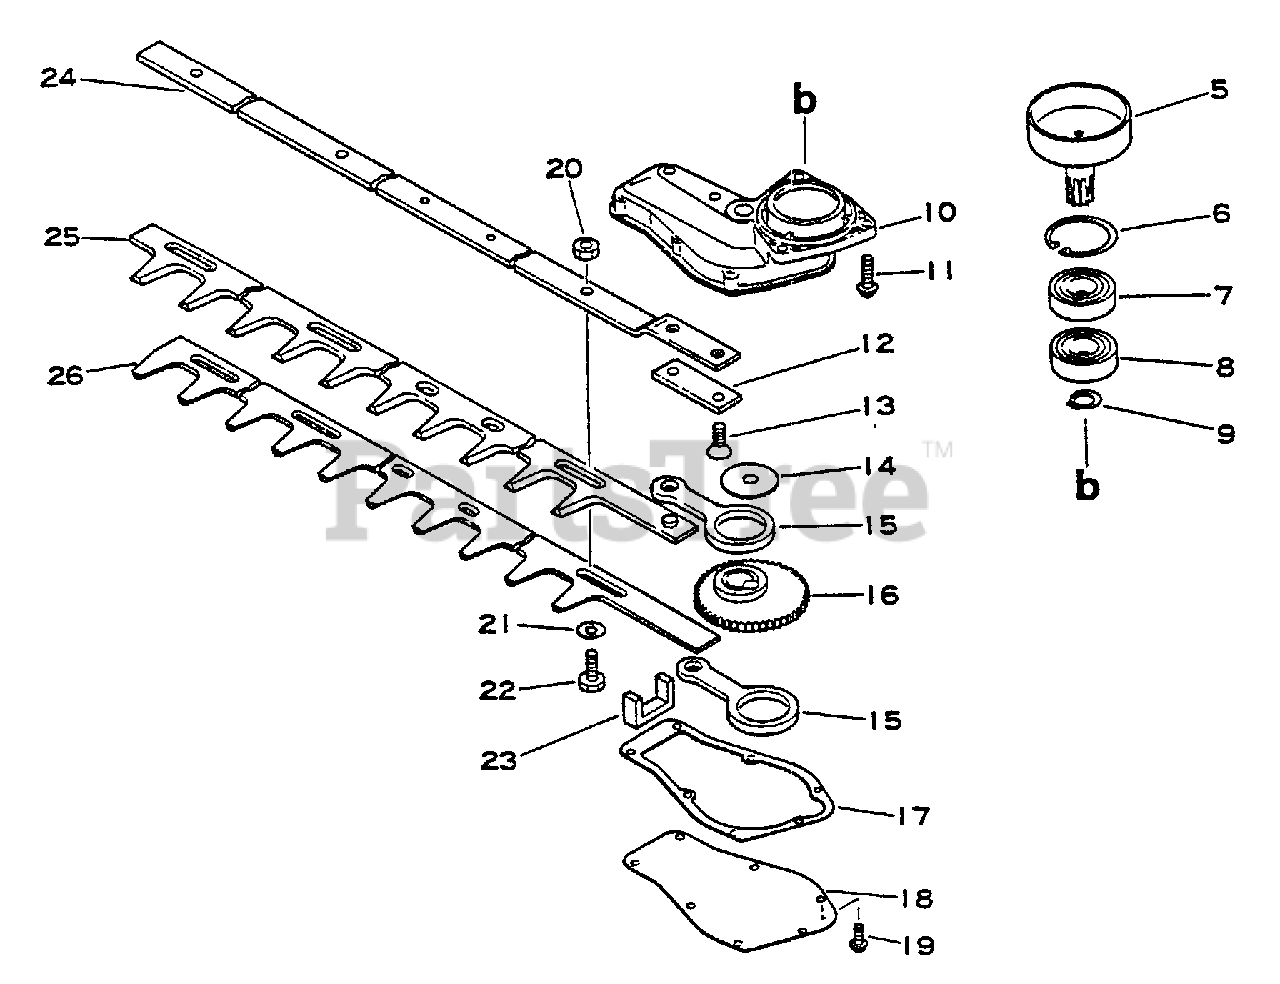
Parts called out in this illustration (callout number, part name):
5	DRUM, CLUTCH
6	RING, SNAP 35
7	BEARING, BALL 6202
8	BEARING, BALL 6202
9	RING, SNAP 14
10	CASE, GEAR
11	SCREW 5×20
12	PLATE, EYE
13	SCREW 6×18
15	ROD, CONNECTING
17	GASKET, GEAR CASE
18	LID, GEAR CASE
19	SCREW 4×10
20	NUT, LOCK 6
21	WASHER 6.5×15.5×0.6
22	BOLT, CUTTER
24	BAR, FRAME
25	CUTTER, UPPER
26	CUTTER, LOWER
